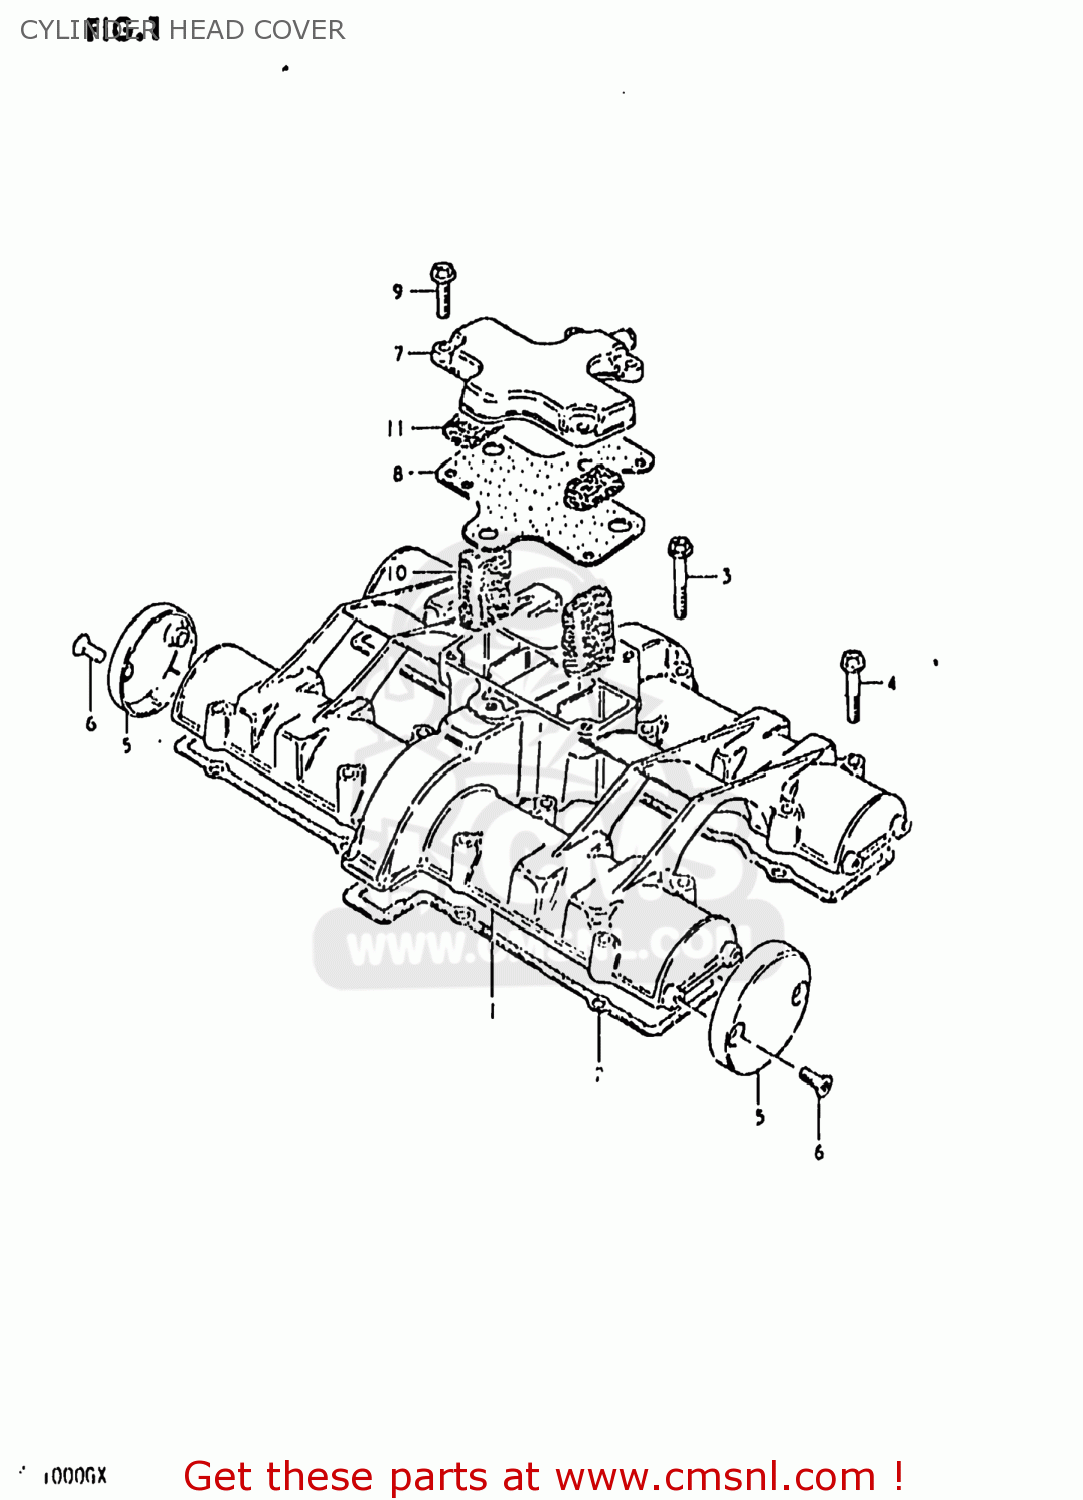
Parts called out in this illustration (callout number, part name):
1	COVER,CYLINDER HEAD
2	GASKET,CYLINDER HEAD COVER (MCA)
3	BOLT
4	BOLT 6X35
5	CAP,CYLINDER HEAD COVER
6	SCREW 5X12
7	COVER,BREATHER
8	GASKET (MCA)
9	BOLT
10	COVER,BREATHER
11	SEPARATOR,OIL BREATHER
